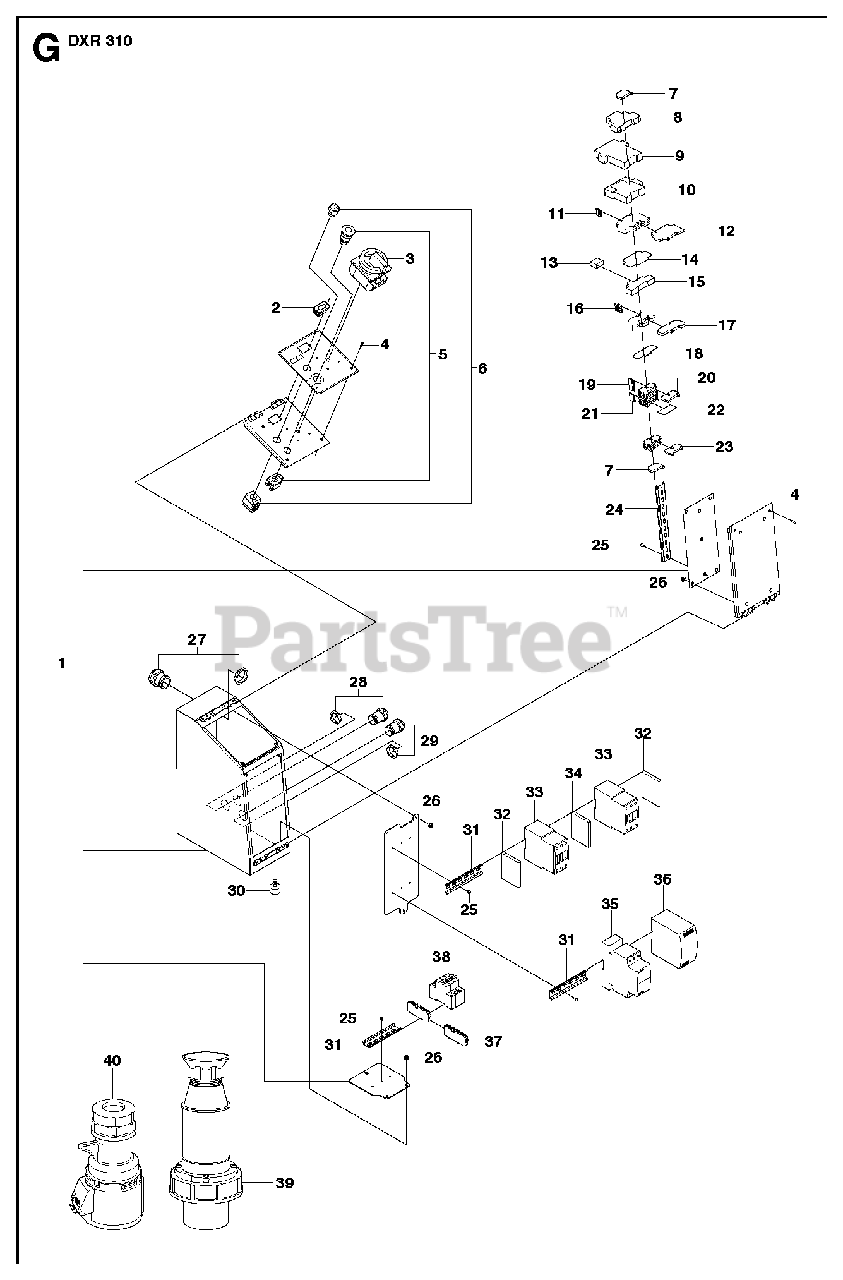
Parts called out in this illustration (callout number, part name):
8	CONTROLT3, Fan control relay
9	RELAYB1, Safety relay
10	RELAYK1, Phase sequence relay
25	SCREW SLPANM
